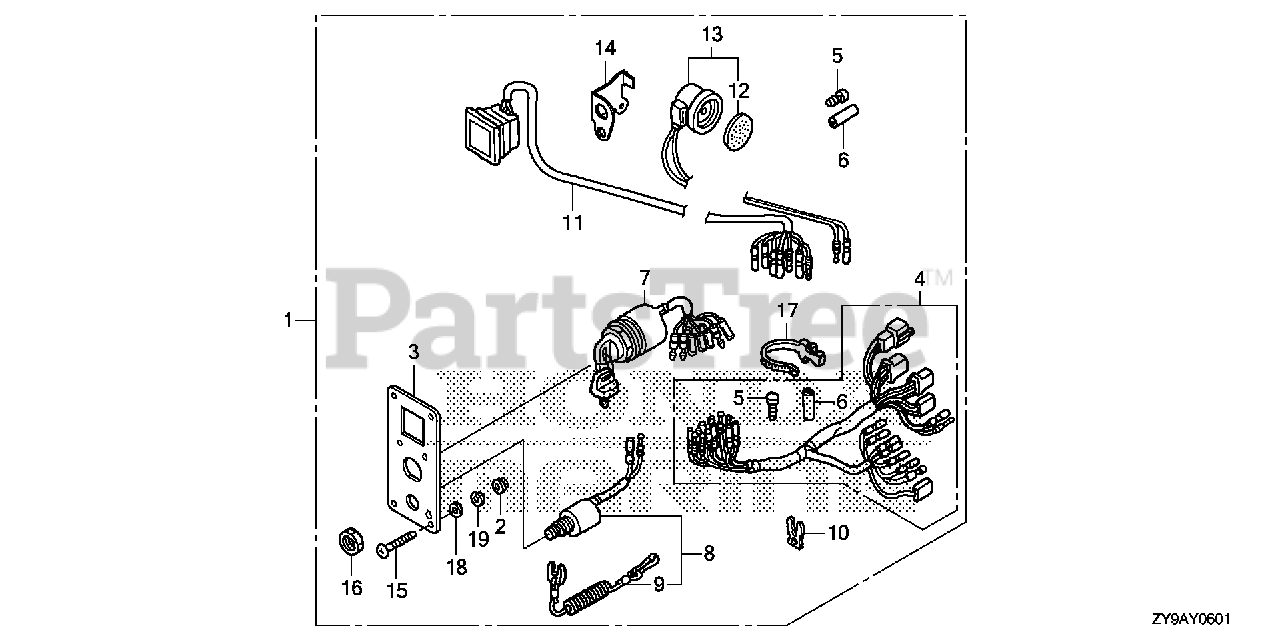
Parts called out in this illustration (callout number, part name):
1	PANEL KIT, SWITCH (4-LED)
2	NUT, FLANGE (5MM) DUAL QTY = (8) (SINGLE)
3	PANEL, CONTROL
4	HARNESS ASSY., SWITCH PANEL
5	PLUG, CONNECTOR (INNER) (TROLLING CONTROL)
6	PLUG, CONNECTOR (OUTER) (ENGINE NO.)
7	SWITCH ASSY., COMBINATION (SINGLE) (DUAL)
8	SWITCH ASSY., EMERGENCY STOP
9	WIRE, EMERGENCY (SINGLE) (DUAL)
10	CLIP, EMERGENCY LOCK
11	LAMP ASSY., INDICATION (4-LED)
12	PLATE, TURN SIGNAL BUZZER DUAL QTY = (2) (SINGLE)
13	BUZZER, WARNING DUAL QTY = (2) (SINGLE)
14	BRACKET, BUZZER
15	SCREW, PAN (5X40) DUAL QTY = (8) (SINGLE)
16	NUT, HEX. (16MM) DUAL QTY = (2) (SINGLE)
17	BAND, WIRE HARNESS (150MM) (NATURAL) DUAL QTY = (2) (SINGLE)
18	WASHER, PLAIN (5MM) DUAL QTY = (8) (SINGLE)
19	WASHER, SPRING (5MM) DUAL QTY = (8) (SINGLE)
